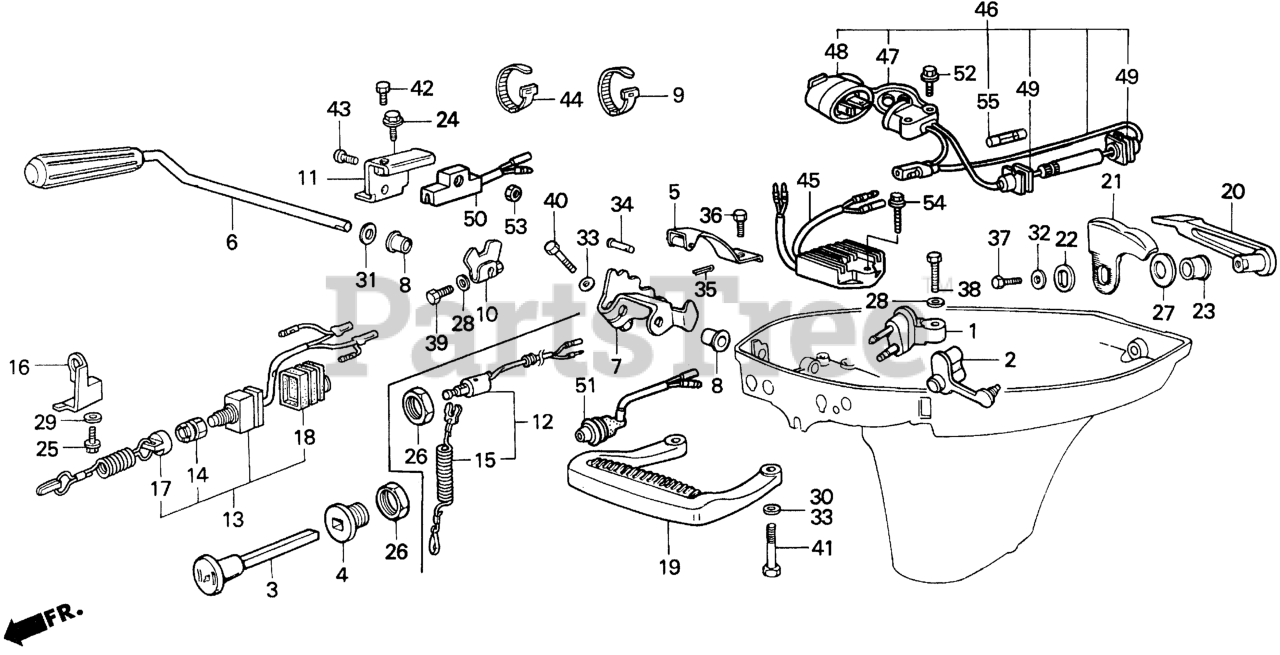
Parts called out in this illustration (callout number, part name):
1	CONNECTOR, FUEL *B9* (ATLANTIS BLUE) (NOT AVAILABLE)
2	CAP, FUEL JOINT
3	KNOB, CHOKE
4	GUIDE, CHOKE KNOB
5	SPRING, CLICK
6	SHAFT, SHIFT
7	ARM, GEARSHIFT
8	BUSH, SHAFT
10	PLATE, SWITCH SHIELD
11	PLATE, SWITCH SETTING
19	HANDLE, CARRYING *B9* (ATLANTIS BLUE) (NOT AVAILABLE)
20	LEVER, COVER LOCK *B9* (ATLANTIS BLUE) (NOT AVAILABLE)
21	HOOK, COVER LOCK
22	WASHER, COVER LOCK
23	BUSH, COVER LOCK
24	BOLT, FLANGE (6X12)
26	NUT, HEX. (16MM) DUAL QTY = (2) (SINGLE)
27	SPRING, LEVER
28	WASHER, PLAIN (6MM) Use from Frame SN 4800713.
31	WASHER, PLAIN (10MM)
32	WASHER (6MM)
33	WASHER, PLAIN (8MM) Use from Frame SN 4800713.
34	PIN (5X17)
35	PIN, COTTER (1.6MM)
36	BOLT, HEX. (6X12)
37	BOLT, HEX. (6X16)
38	BOLT, HEX. (6X20)
39	BOLT, HEX. (6X28)
40	BOLT, HEX. (8X28)
41	BOLT, HEX. (8X32) (NOT AVAILABLE)
43	SCREW, PAN (5X20)
44	BAND B1, CABLE
